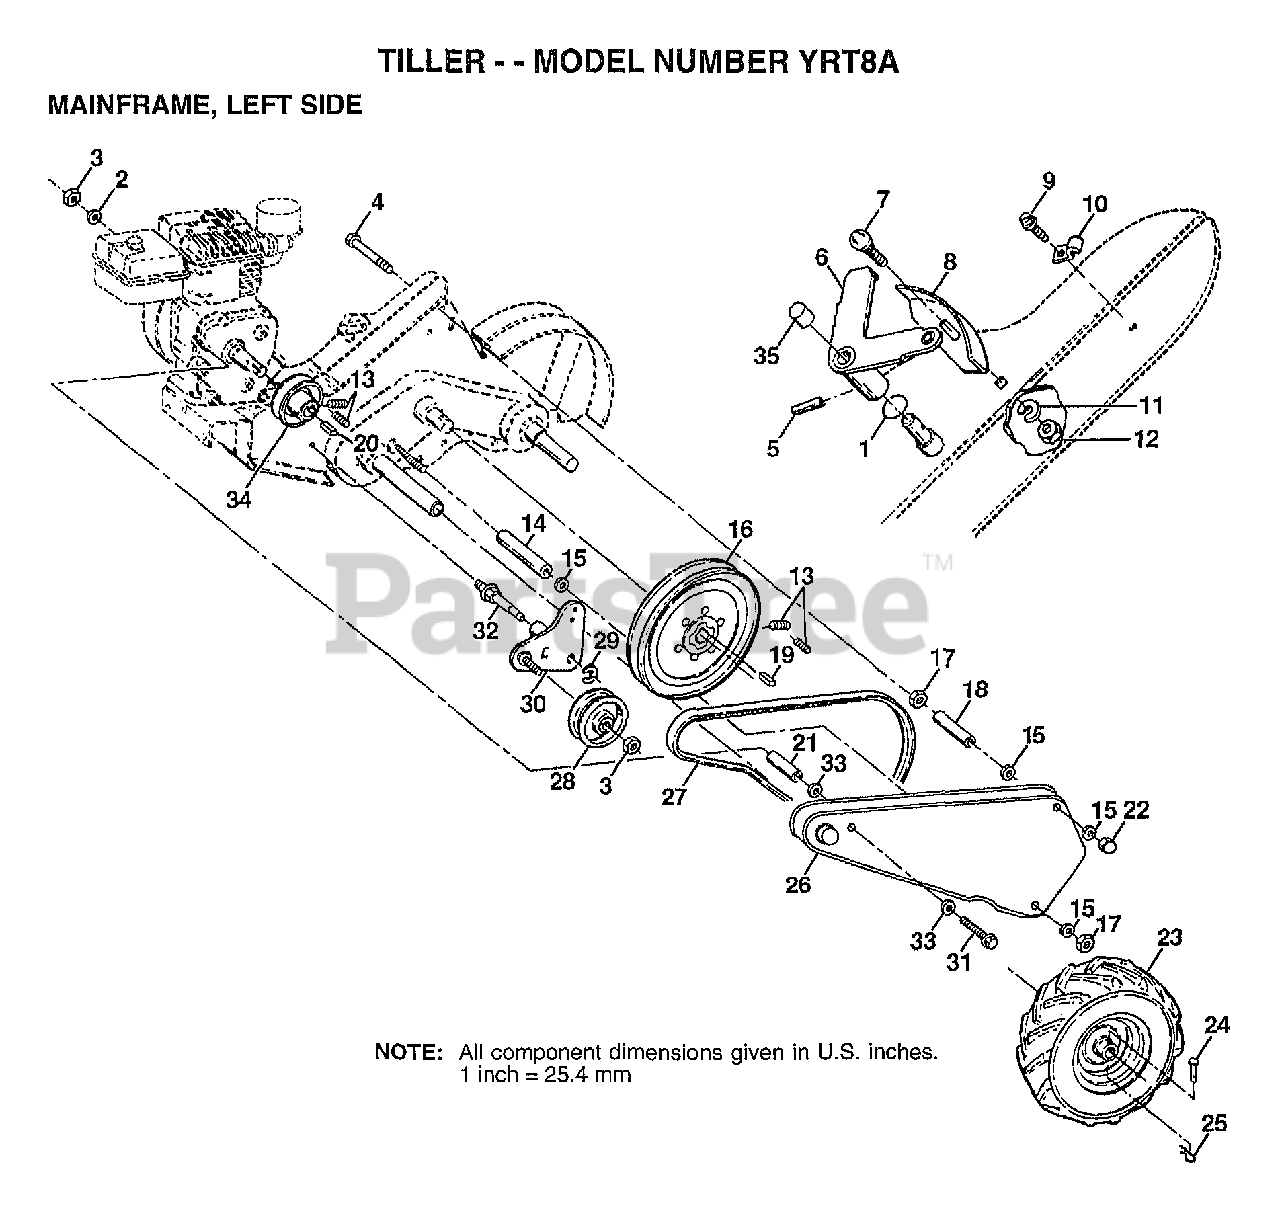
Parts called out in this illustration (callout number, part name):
1	O-RING TI
2	LOCKWASHER
3	NUT.HEX.3/8-16UNC
4	BOLT TI
6	LEVER ASM CRT
7	BOLT
8	PANEL TI
10	CONDIUT CLIP T
11	LOCKWASHER
13	SET SCREW
14	SPACER TI
15	WASHER
16	"SHEAVE 10"" CRT"
17	NUT.HEX.5/16-18
18	SPACER TI
19	KEY T
20	KEY TI
21	SPACER.SPLIT
22	NUT TI
23	TIRE TI
23	WHEEL TI
24	RIVET.PAN HD.1.75
25	SPRING.RETAINER
26	GUARD BELT RED
27	BELT.DRIVE
29	KLIP RING
31	BOLT1/2-20UNF2.75
32	SHAFT.IDLER
34	SHEAVE CRT
35	CAP PLUNGER BLACK
